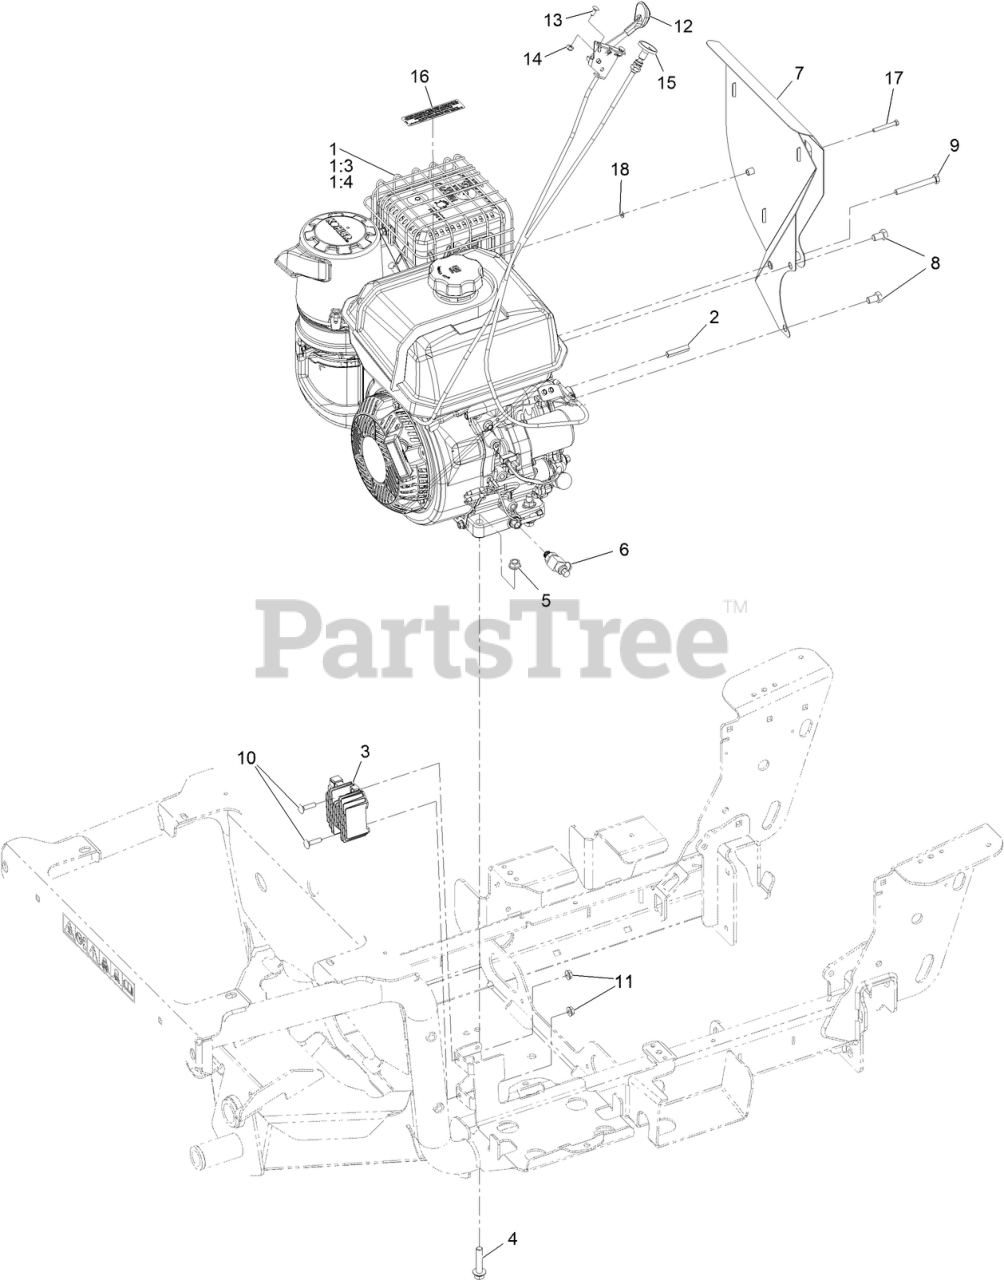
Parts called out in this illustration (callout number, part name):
1	ENGINE-KOHLER, CH395
1:3	CAGE-CH395 17_314_197 BIRD
1:4	DEFLECTOR-EXHAUST, KOHLER
2	KEY-SQUARE, 7MM
3	REGULATOR-TROMBETTA, 18A
4	SCREW-HHF
5	NUT-HF
6	VALVE-DRAIN, OIL
7	HEAT SHIELD ASM
8	SCREW-HH
9	SCREW-HH
10	SCREW-CARR
11	NUT-HF
12	CONTROL-THROTTLE
13	BOLT-CARR
14	NUT-LOCK, NI
15	CABLE-CHOKE, PUSH/PULL
16	DECAL-ARRESTOR, SPARK
17	BOLT-M5X0.8MM X 40 MM LONG
18	WASHER-FLAT
